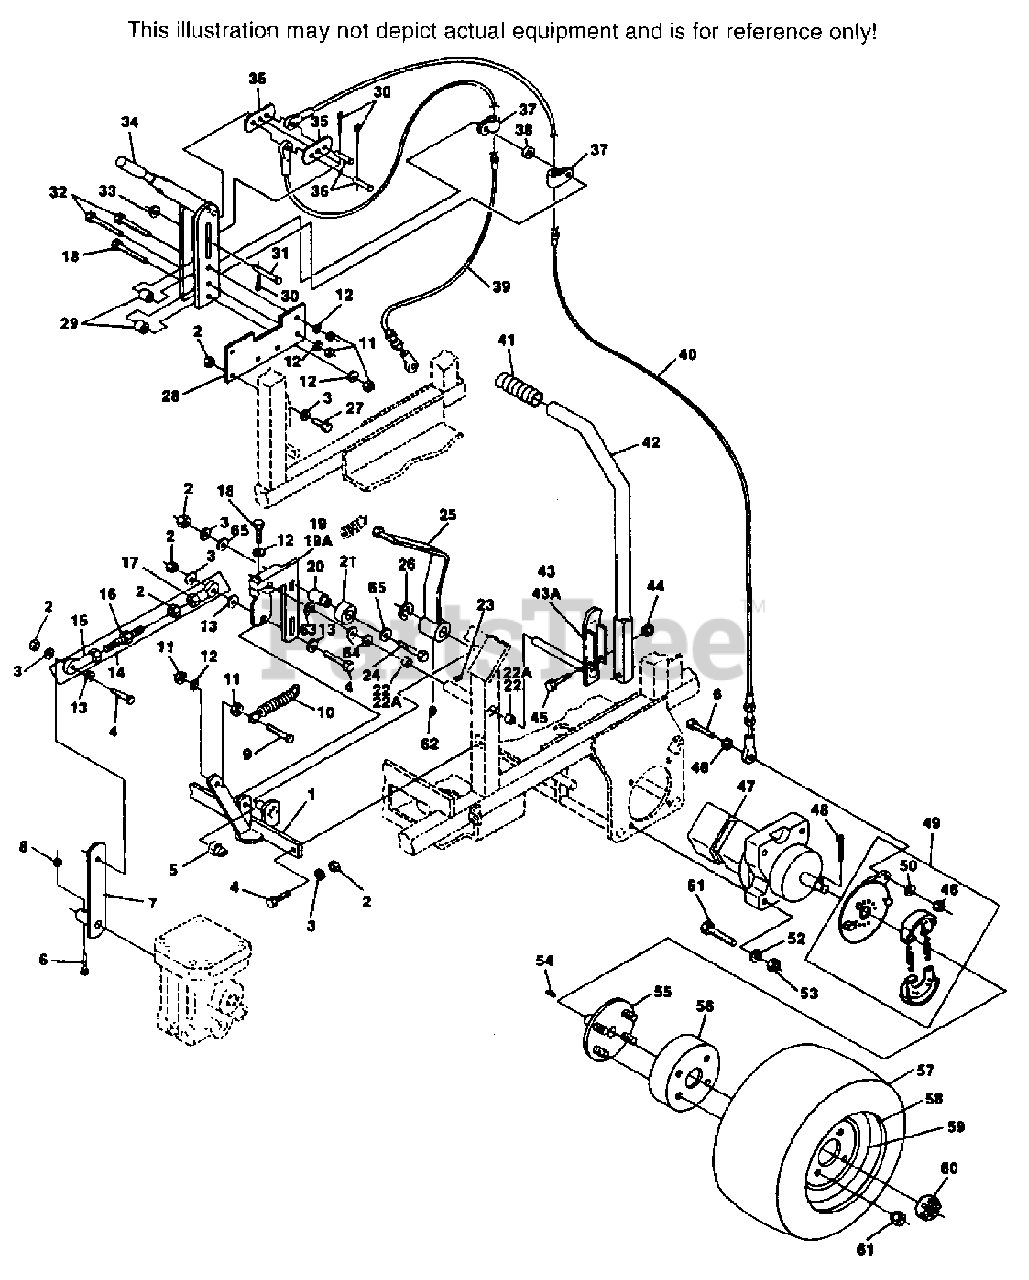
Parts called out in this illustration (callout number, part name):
1	NEUTRAL CONTROL
5	SWITCH, NEUTRAL
7	LEVER, PUMP CONTROL
8	HEX NUT, 1/4-20 ELASTIC STOP
10	SPRING, NEUTRAL
13	FLAT WASHER, 3/8
14	TURNBUCKLE ASSEMBLY
15	BALL JOINT, LH THREAD(GOLD)
16	LINK, TURNBUCKLE
17	BALL JOINT, RH THREAD(SILVER)
19	LEVER, PUMP TRANSFER - RH
19A	LEVER, PUMP TRANSFER - LH
20	SPACER, NEUTRAL BEARING
21	BEARING, NEUTRAL RETURN
22	BUSHING - LH
22A	BUSHING - RH
23	GREASE FITTING
25	NEUTRAL CAM(INCLUDES GREASE FTG.)
26	RETAINING RING, 5/8 EXTERNAL "E"
28	BRAKE EXTENSION BAR
29	SPACER
30	COTTER PIN
33	WASHER
34	BRAKE LEVER ASSEMBLY, COMPLETE
35	EQUALIZER
38	SPACER
39	BRAKE CABLE - RH
40	BRAKE CABLE - LH
41	GRIP, CONTROL HANDLE
42	CONTROL HANDLE(INCLUDES GRIP)
43	CONTROL LEVER - RH
43A	CONTROL LEVER - LH
44	HEX NUT, 5/16-18 ELASTIC STOP
47	MOTOR, WHITE
49	PARKING BRAKE ASSEMBLY
54	KEY, 5/16 X 5/16 X 15/16
55	WHEEL HUB ASSEMBLY
56	BRAKE DRUM
57	WHEEL ASSEMBLY
58	TIRE ONLY
59	RIM ONLY
60	HEX CASTLE NUT
61	NUT AND BOLT
62	GREASE FITTING
63	RETAINING RING, 3/4 EXT "E"
64	FLAT WASHER
